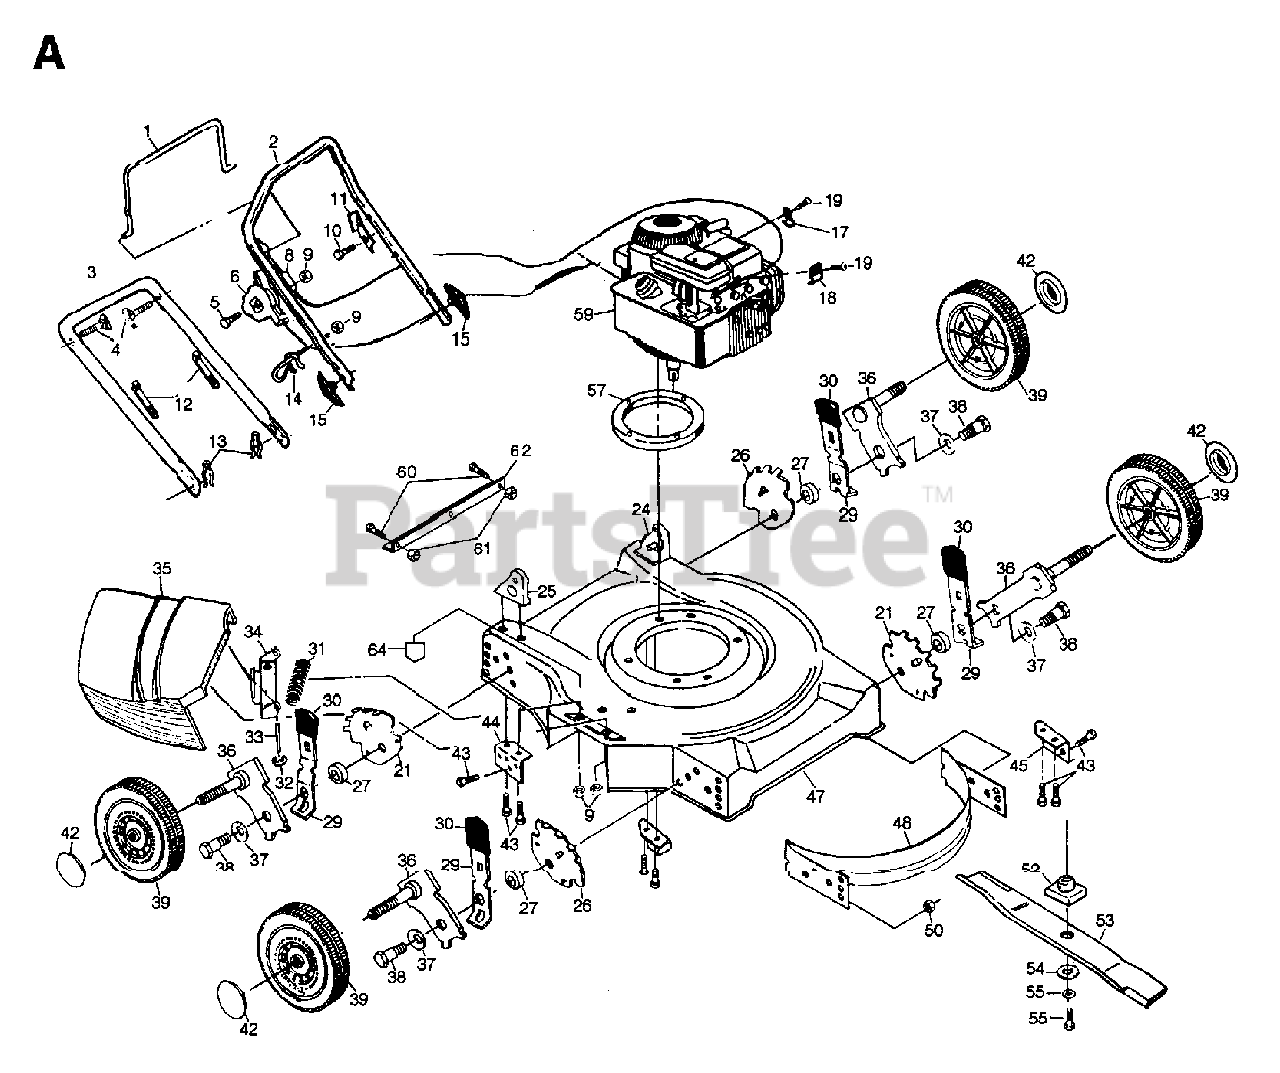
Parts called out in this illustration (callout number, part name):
1	CONTROL BAR/BLACK
2	UPPER HANDLE
4	HANDLE BOLT
5	SCREW 1/4-20 X 2.12
6	THROTTLE CONTROL
8	ENGINE ZONE CONTROL CABLE
9	NUT
10	TAPPING SCREW
11	BRACKET UPSTOP
12	CLIP CABLE SNAP
13	HAIRPIN COTTER
14	ROPE GUIDE
15	HANDLE KNOB
18	GUIDE CLIP PM
19	SCREW.HEX.HEAD.WASHER.10-16
21	BRACKET.WHL.ADJ.L
24	HDLE BRKT ASSY LH
25	HDLE BRKT ASSY RH
26	BRACKET.WHL.ADJ.R
27	RP SPACER HT ADJ
29	SELECTOR SPRING
31	SPRING PM
33	ROD.HINGE.COMBI-C
34	BRACKET PM
36	AXLE, REAR
37	BELLEVILLE WASHER
38	BOLT
43	SELF-TAPPING SCREW 5/16-18X3/4
50	LOCKNUT PM
52	BLADE ADAPTOR
53	BLADE.20.MULCH.(50DK,6020MD)
54	WASHER,HARDEN
55	LOCKWASHER
56	SCREW, HEX HD 3/8-24 X 1-3/8
58	DECAL MOWER CUT/FINGER
